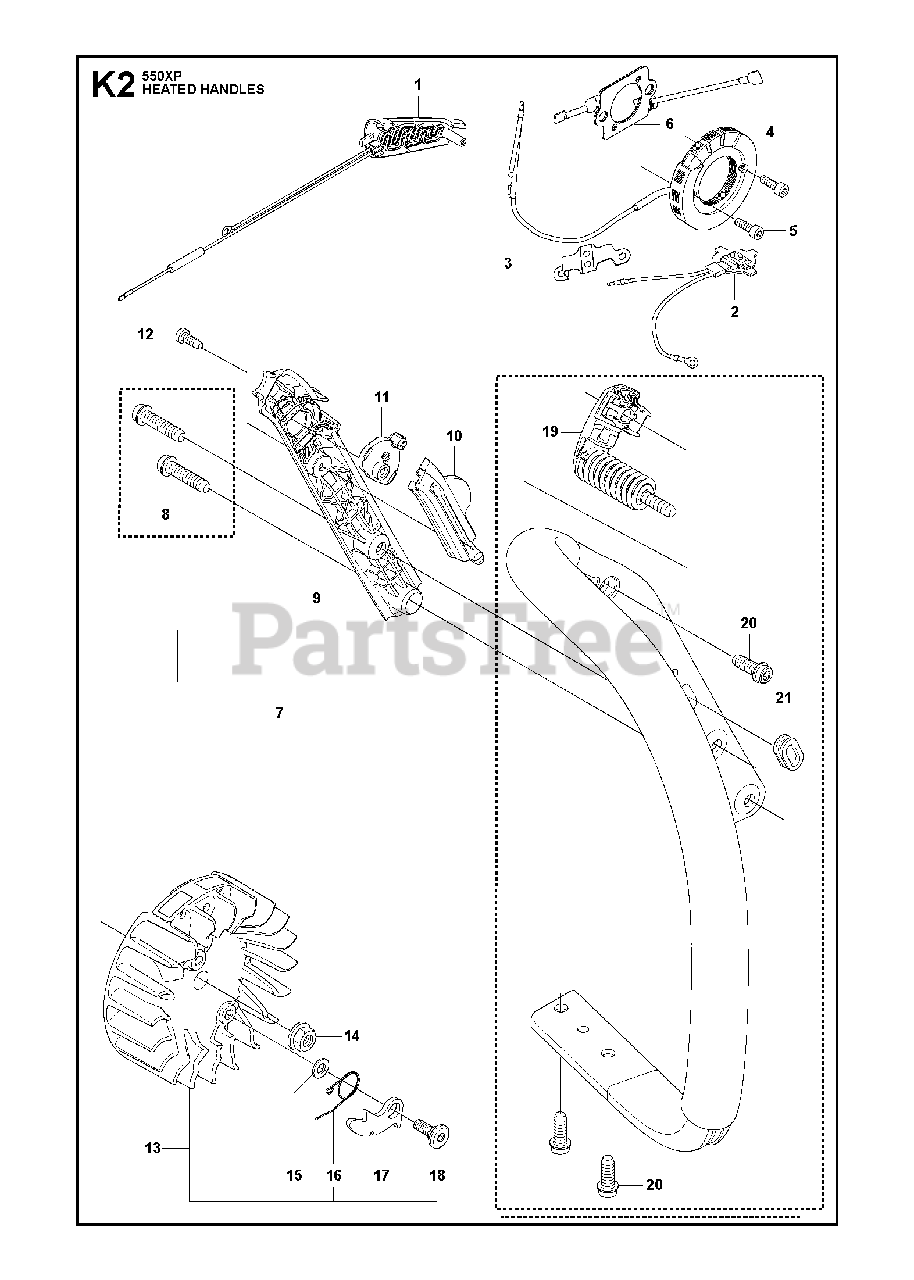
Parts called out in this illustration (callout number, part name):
1	HANDLE INSERT
2	THERMOSTAT ASSY
4	GENERATOR STATOR
6	FOIL ELEMENT
7	FRONT HANDLE
8	SCREW
10	CONTACT PLATE
13	FLYWHEEL ASSY
14	NUT W/ WASHER
15	WASHER
16	SPRING
17	PAWL
18	SCREW M5X14
19	ANTIVIBRATION ELEMENT
20	SCREW IHSCFT
21	GROMMET
